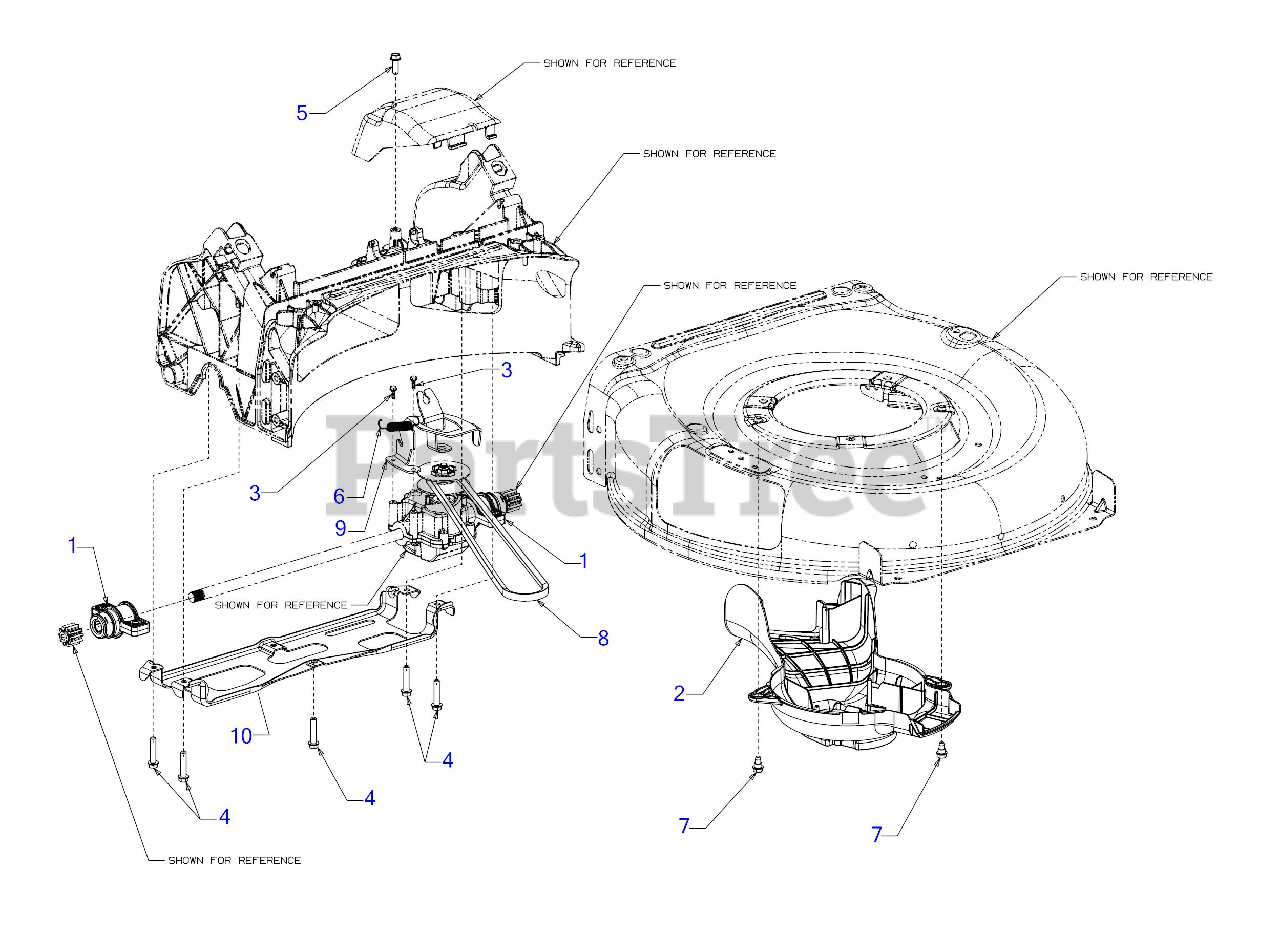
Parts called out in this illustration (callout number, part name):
1	BEARING ASSEMBLY
2	AWD ENGINE BAFFLE ASSEMBLY
3	SCREW .159 x .43
4	SCREW 1/4-15 x 1.250
5	SCREW 1/4-15 x .750
6	EXTENSION SPRING
7	SHOULDER SCREW 1/4-20 x .50
8	V-BELT 31.25
9	TRANSMISSION BRACKET
10	SUPPORT BRACKET
